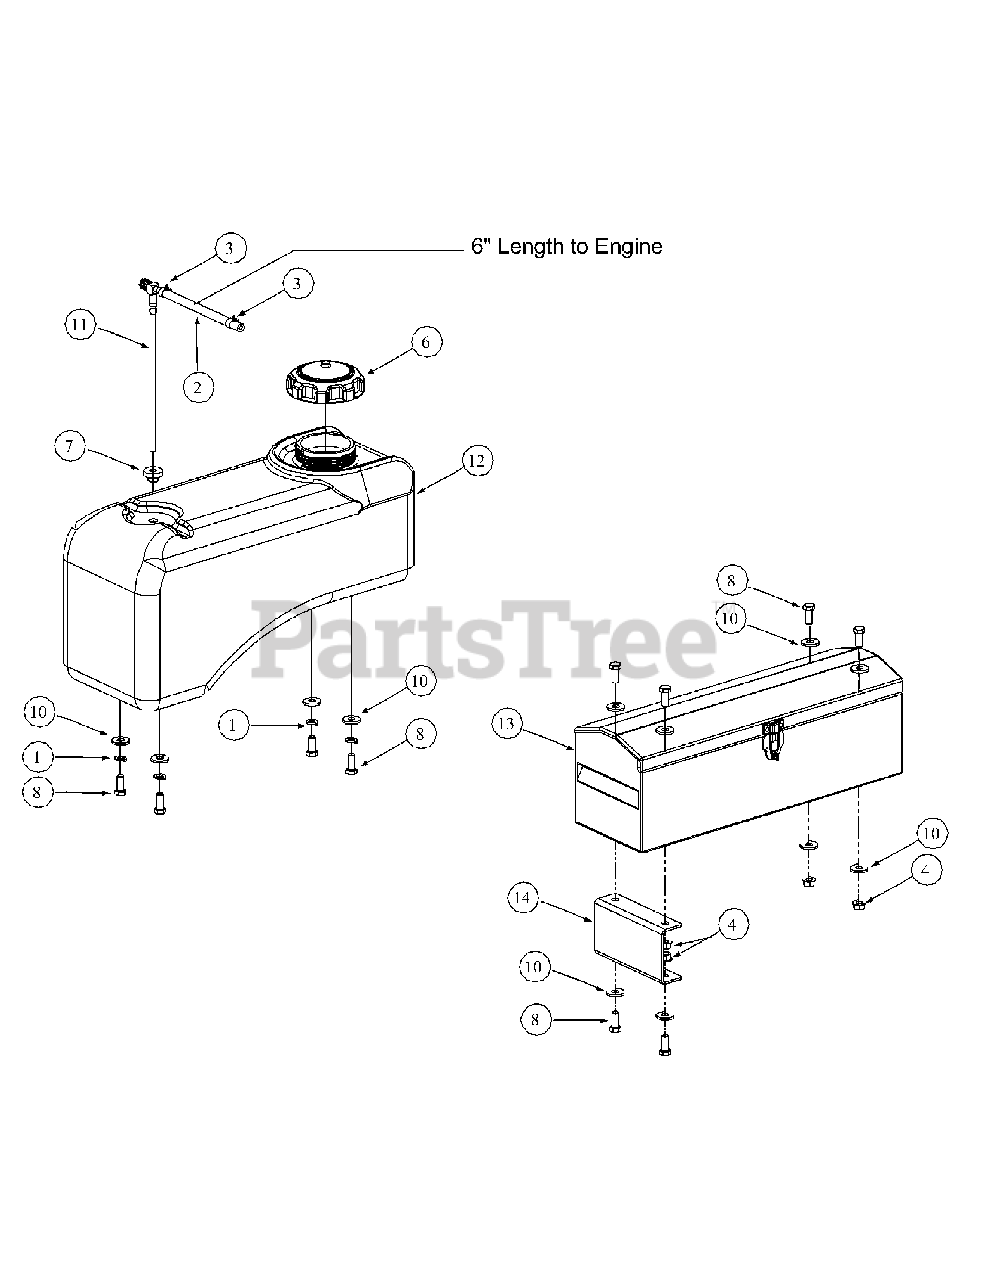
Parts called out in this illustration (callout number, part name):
1	Lock Washer, 3/8
3	Clamp
4	Flange Lock Hex Nut, 3/8-16
6	Fuel Cap, 3.5
7	Fuel Tank Grommet
8	Hex Cap Screw, 3/8-16, .88
9	Decal, Tool Box "Parts Info"
10	Flat Washer, .406 ID, 1.0 OD, .105
11	Fuel Fitting
12	Fuel Tank
13	Toolbox
14	Toolbox Mount Bracket
